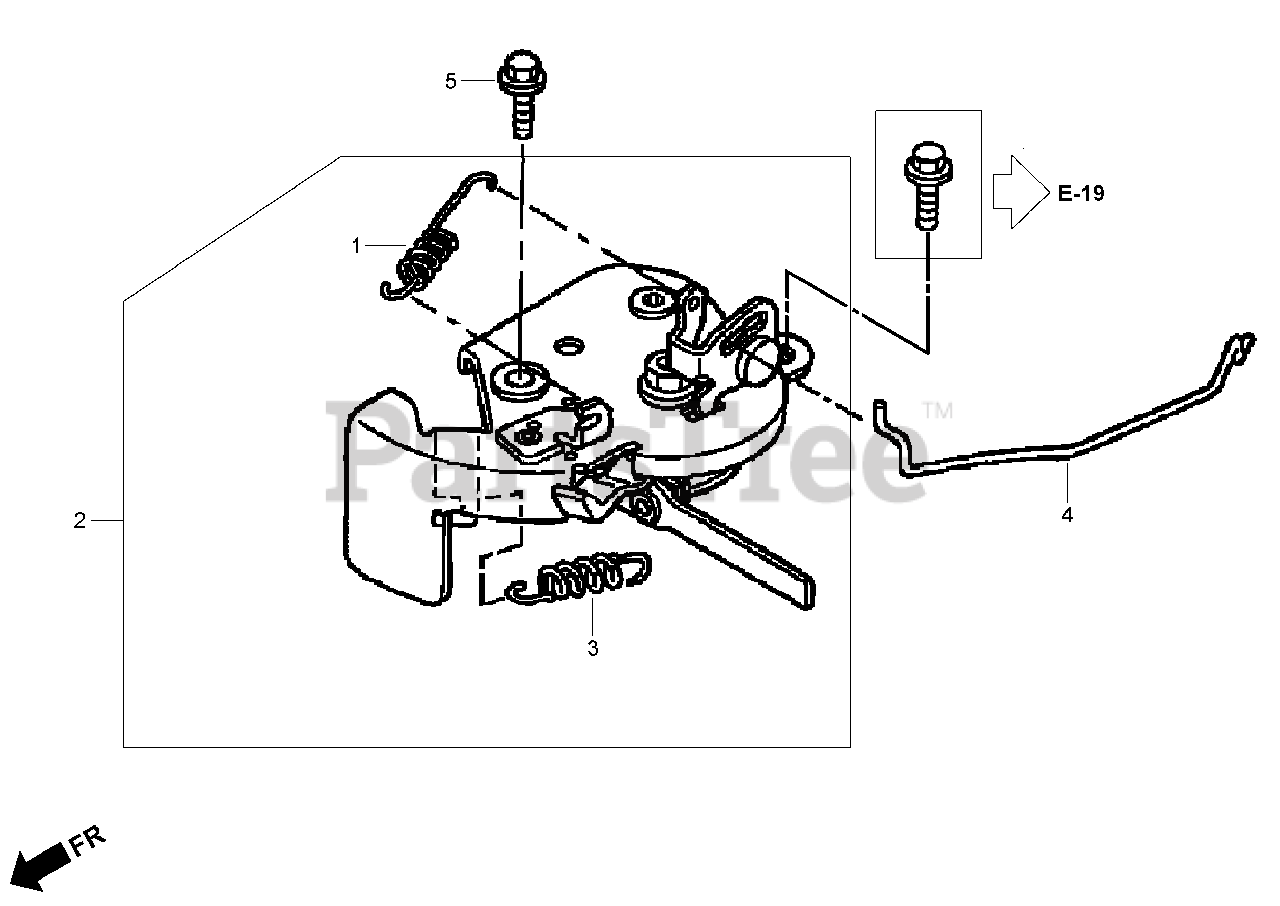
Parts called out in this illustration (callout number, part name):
1	SPRING-RETURN
2	CHOKE LEVER ASM
3	SPRING-LEVER, CHOKE
4	ROD-STOP
5	BOLT-FLANGE (6X16) (C T200)
